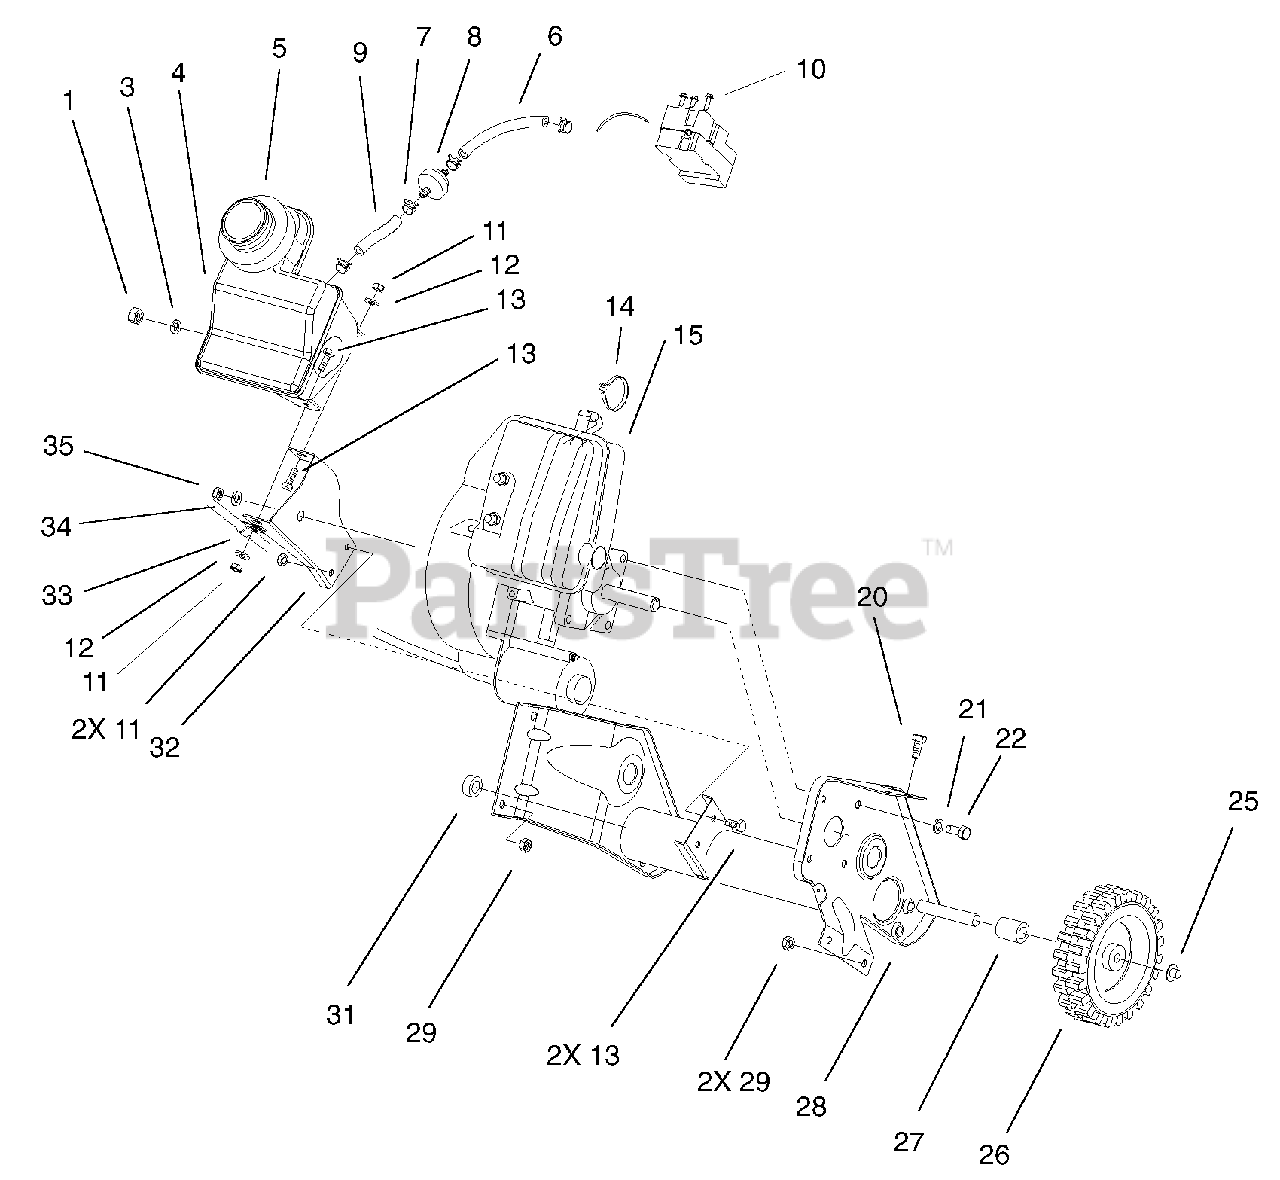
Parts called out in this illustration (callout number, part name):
1	NUT-LOCK, CONE
3	GROMMET-RUBBER
4	Tank-Gas
5	SEAL-FOAM
6	LINE-FUEL
8	FILTER-FUEL
9	HOSE-FUEL
11	NUT-LOCK, NI
12	WASHER-FLAT
13	SCREW-HH
14	TIE-CABLE
20	SCREW-HH
21	WASHER-BELLEVILLE
22	SCREW-HH
27	SPACER-WHEEL
29	NUT-LOCK, NI
31	SPACER-WHEEL
32	SUPPORT-RECOIL
34	WASHER-SUPPORT, ENGINE
35	NUT-LOCK, NI
